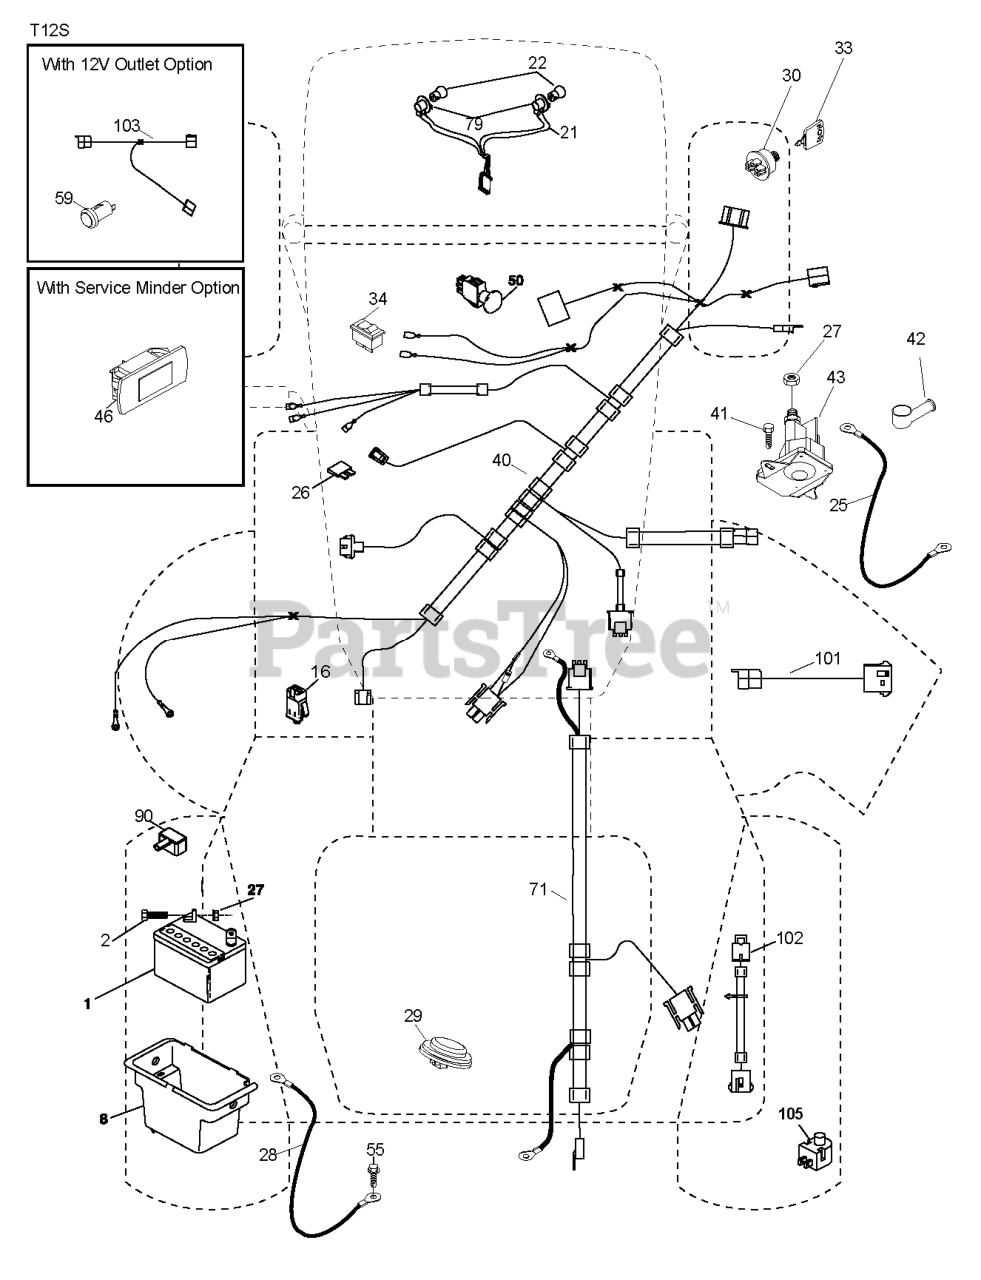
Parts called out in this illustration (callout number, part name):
1	Battery 12 Volt 25 Amp
2	BOLT.HEX.1/4.X.3/4.DICHROMATE
8	BOX.BATTERY.MNT.REAR.L
16	SWITCH INTERLOOK PUSH-IN
21	HARNESS.LIGHT W/4152J BULBS
25	CABLE.STARTER.6GA.BL/RED.14.
26	FUSE 20AMP
27	NUT
28	CABLE.BLACK.18"REAR.BA
29	SWITCH.SEAT.DELTA.OPC.
30	SWITCH.IGN.DELTA.W.LGH.ROS
33	KEY.CHAIN.BLISTER.PACK.GEN.USA
40	HARNESS.IGN.DASH.HUQ/P
41	SCREW
42	TERMINAL COVER
43	SOLENOID.W/BRASS.PLUNGER
46	RP.GUAGE.SRVCMNDR.HRMTR.
50	RP.PTO.SWITCH.8 TERMINAL.BLACK
55	SCREW 5/16"
71	HARNESS.IGN.CHASS.TEX.REAR.BAT
79	BULB HOLDER ASM.
90	COVER, TERMINAL BATTERY
101	PIGTAIL.MATNLK.NEW.HAR
102	HARNESS PIGTAIL PCH TEX ROS
105	REVERSE SWITCH
